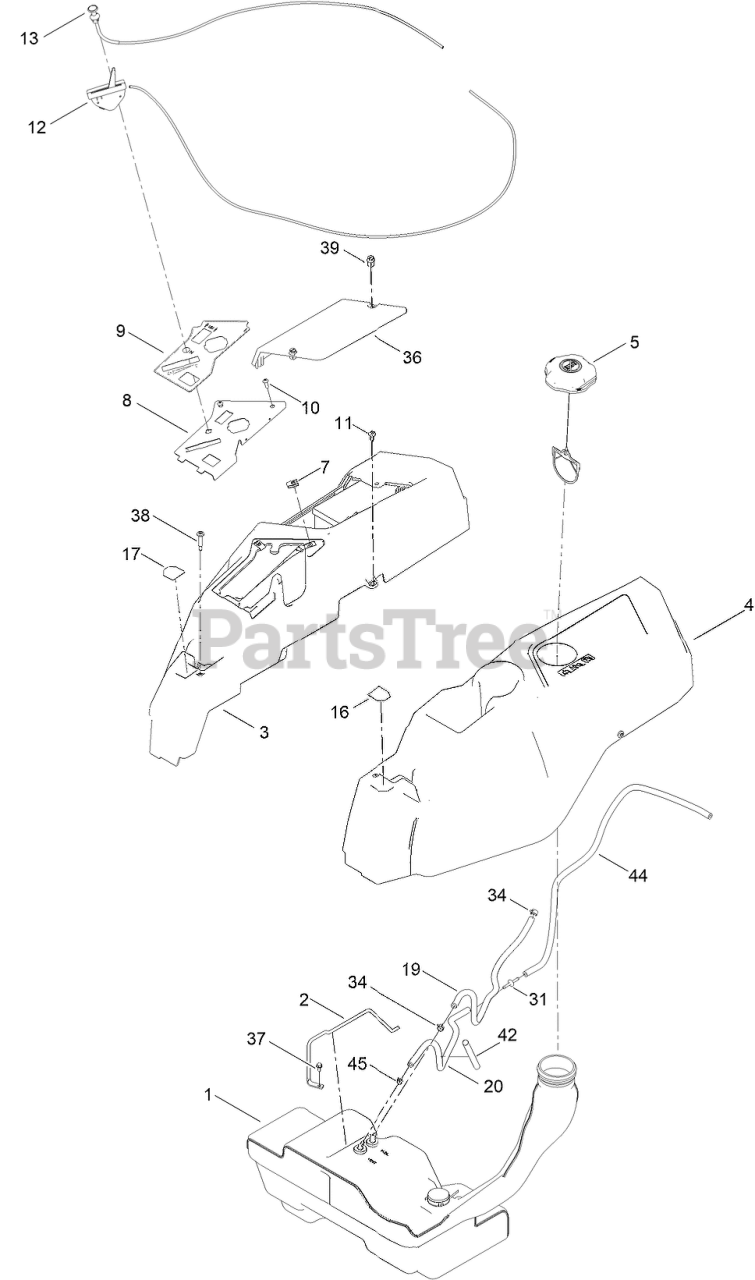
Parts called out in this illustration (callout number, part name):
1	TANK-FUEL ASM
2	ROD-HOLD DOWN
3	POD-RH
4	POD-LH
5	CAP-FUEL, RATCHETING
8	PANEL-CONTROL
9	DECAL-PANEL, CONTROL
10	SCREW-PRH
11	SCREW-SHOULDER
12	CABLE-THROTTLE
13	CABLE-CHOKE
16	DECAL-LEVER, CONTROL (LH)
17	DECAL-LEVER, CONTROL (RH)
19	HOSE-FUEL
20	HOSE-VENT
31	ADAPTER ORIFICE
34	CLAMP-HOSE
36	COVER-BATTERY
37	SCREW-HWH
38	SCREW-SHOULDER
39	FASTENER
42	SLEEVE-FUEL LINE PROTECTOR
44	HOSE-FUEL
45	CLAMP-HOSE
